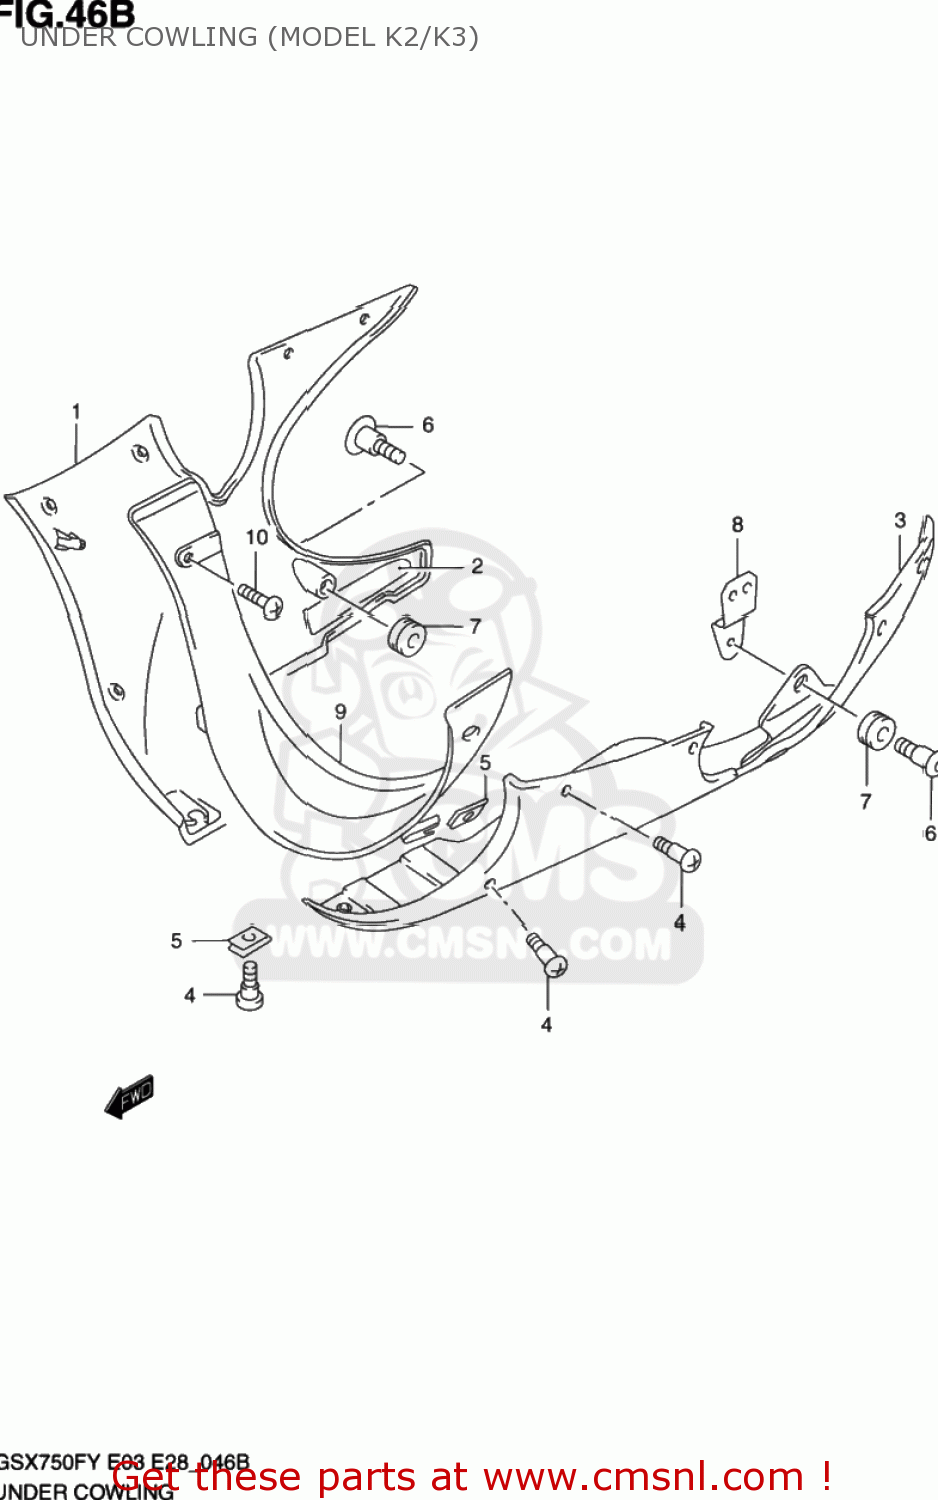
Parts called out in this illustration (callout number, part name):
1	COWLING,UNDER,R(BLACK)
2	SHIELD,COWLING UNDER,R NO.1
3	COWLING,UNDER,L
4	SCREW(5X16)
5	NUT,COWL
6	SCREW(6X20)
7	CUSHION
8	BRACKET,UNDER COWL,L & FRAME
9	COWLING,UNDER CTR
10	SCREW
